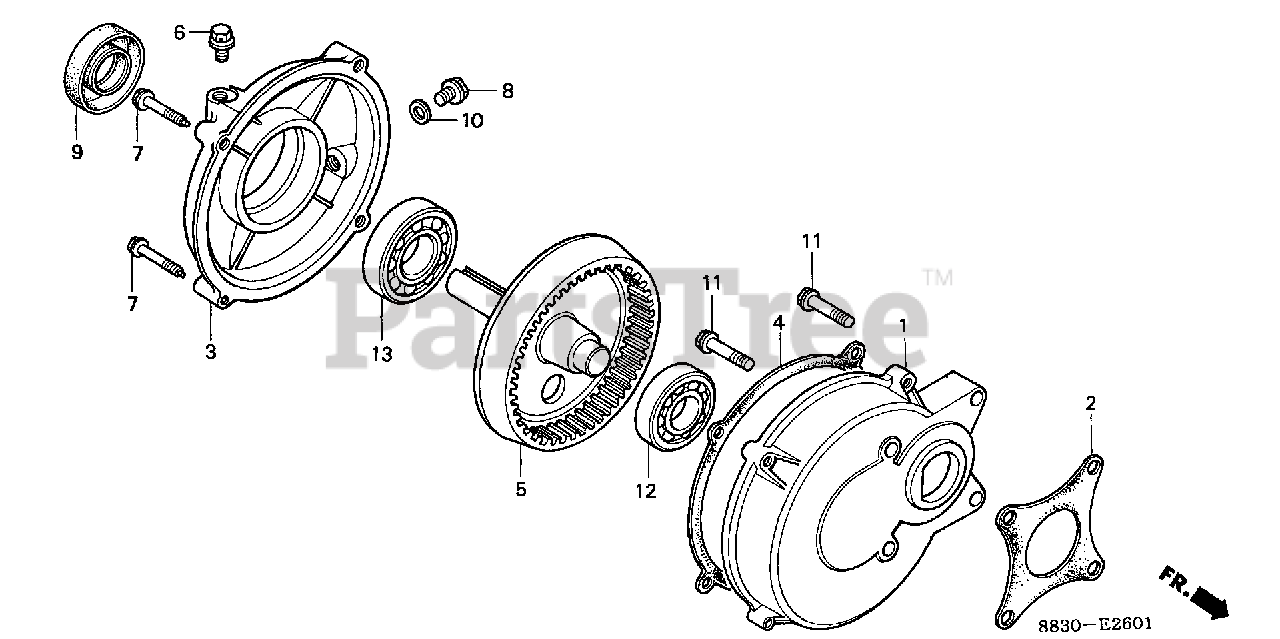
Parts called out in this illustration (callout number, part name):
1	CASE, REDUCTION (NOT AVAILABLE)
1	CASE, REDUCTION
2	GASKET, REDUCTION CASE
3	COVER, REDUCTION (NOT AVAILABLE)
3	COVER, REDUCTION
4	GASKET, REDUCTION COVER
4	GASKET, REDUCTION COVER (NOT AVAILABLE)
5	SHAFT, P.T.O. (86T)
6	BOLT, BREATHING
7	BOLT, FLANGE (6X32)
7	BOLT, FLANGE (8X35)
8	BOLT, DRAIN PLUG (12X15)
9	OIL SEAL (25X41X6)
10	WASHER, DRAIN PLUG (12MM)
11	BOLT, FLANGE (8X32)
12	BEARING, RADIAL BALL (6204)
13	BEARING, RADIAL BALL (6305)
